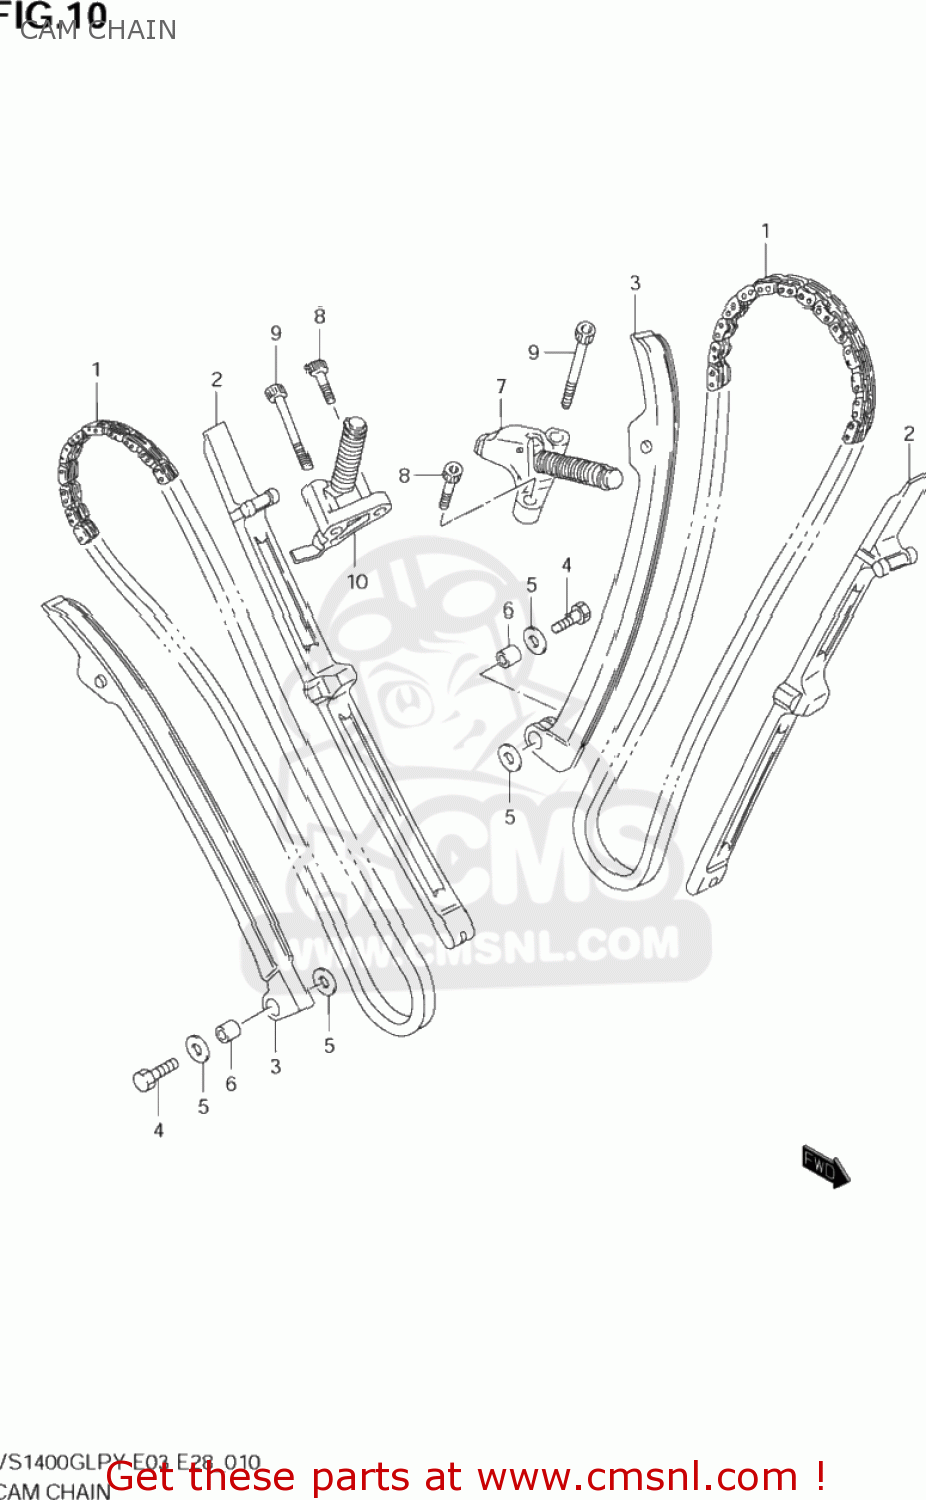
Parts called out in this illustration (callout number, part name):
1	CHAIN,CAMSHAFT DRIVE
2	GUIDE,CAM CHAIN
3	TENSIONER,CAM CHAIN
4	BOLT(6X26)
5	WASHER
6	SPACER(6X11X9)
7	ADJUSTER ASSEMBLY,FRONT TENSIONER
8	BOLT,CRKCASE,R
9	BOLT
10	ADJUSTER ASSEMBLY,REAR TENSIONER
